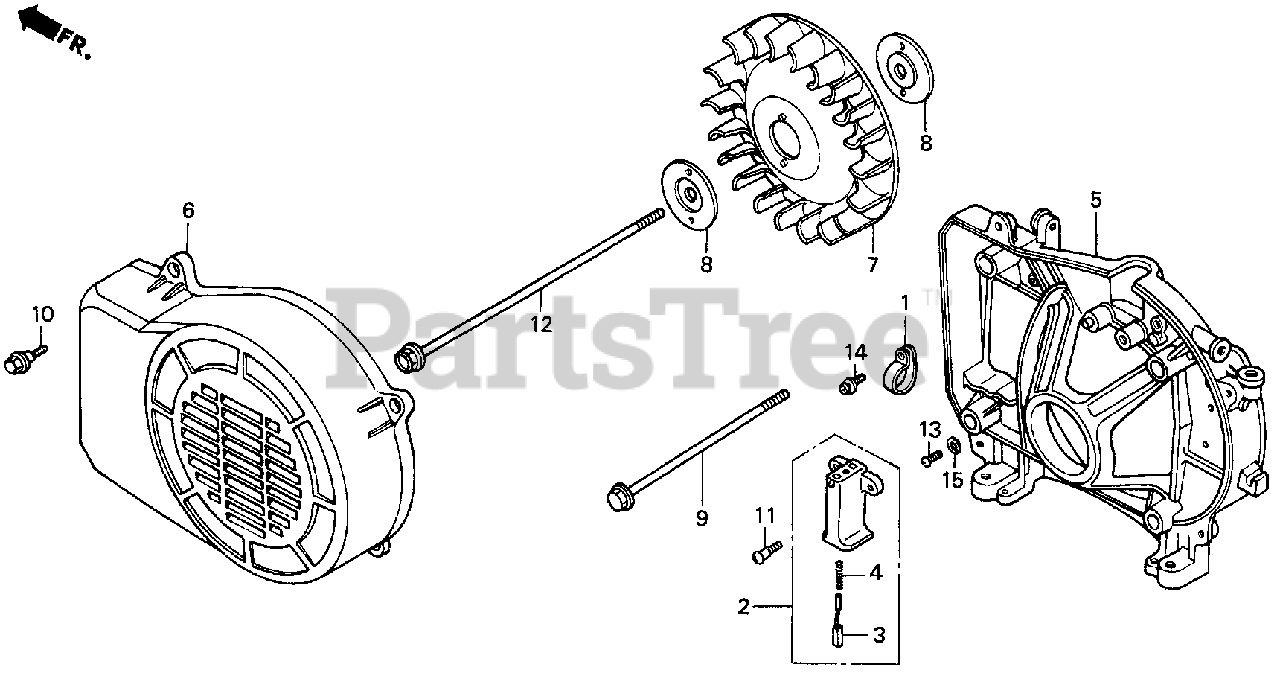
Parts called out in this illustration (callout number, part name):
1	CLAMP C, CABLE
2	HOLDER ASSY., BRUSH
4	SPRING, BRUSH
5	HOUSING, RR.
6	COVER, GENERATOR END
7	FAN, COOLING
8	PLATE, FAN
9	BOLT, FLANGE (6X107)
10	BOLT, GENERATOR END COVER
11	BOLT, STATOR COVER SETTING
12	BOLT, FLANGE (8X145)
13	SCREW, PAN (5X12)
14	SCREW-WASHER (5X12)
15	WASHER, SPRING (5MM)
